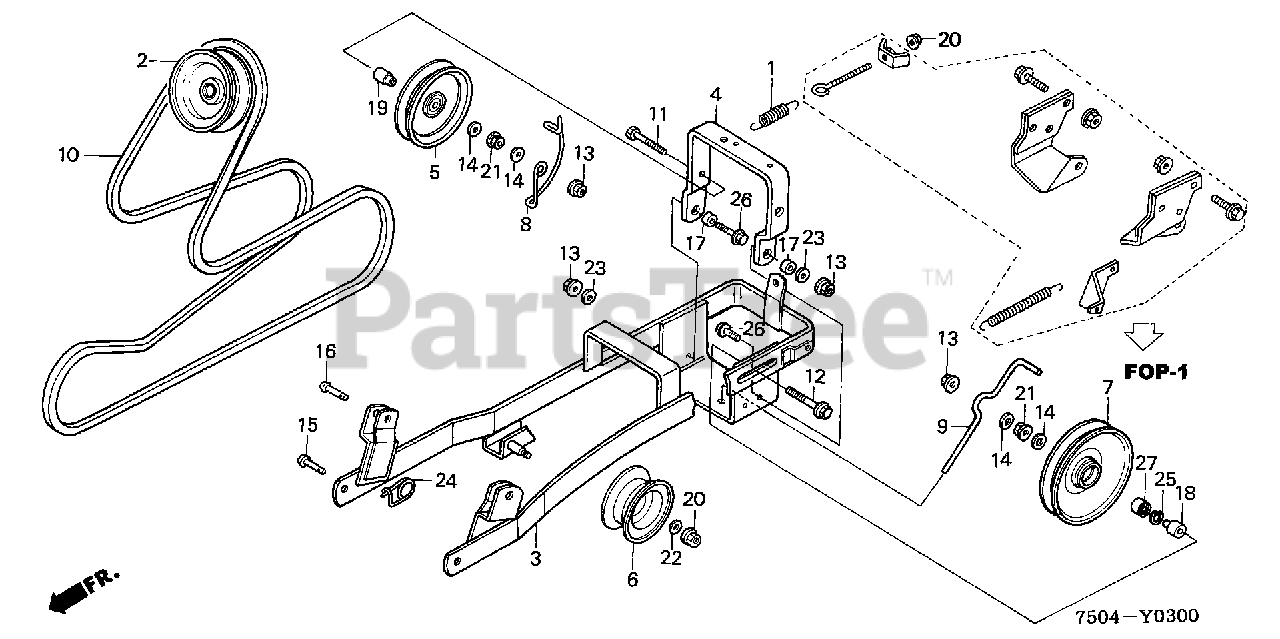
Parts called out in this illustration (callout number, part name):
1	SPRING, BELT TENSIONER
2	PULLEY, ENGINE
4	STAY, PIVOT PULLEY
5	PULLEY, RR. TENSIONER
6	PULLEY, IDLER
7	PULLEY, RR. IDLER
8	STOPPER A, BELT
9	STOPPER, BELT
10	V-BELT (167")
11	BOLT, HEX. (10X69)
12	BOLT, FLANGE (10X87)
13	NUT, U (10MM)
14	WASHER, PLAIN (10MM)
16	PIN (10X31)
17	COLLAR (10.5X16X8)
18	COLLAR, RR. IDLER
19	COLLAR, RR. TENSION PULLEY
20	NUT, FLANGE (8MM)
21	NUT, FLANGE (10MM)
22	WASHER, PLAIN (8MM)
23	WASHER, PLAIN (10MM)
24	PIN, LOCK (10MM)
25	CIRCLIP (INNER) (35MM)
26	BOLT, FLANGE (10X32)
27	BEARING, RADIAL BALL (6202UU)
